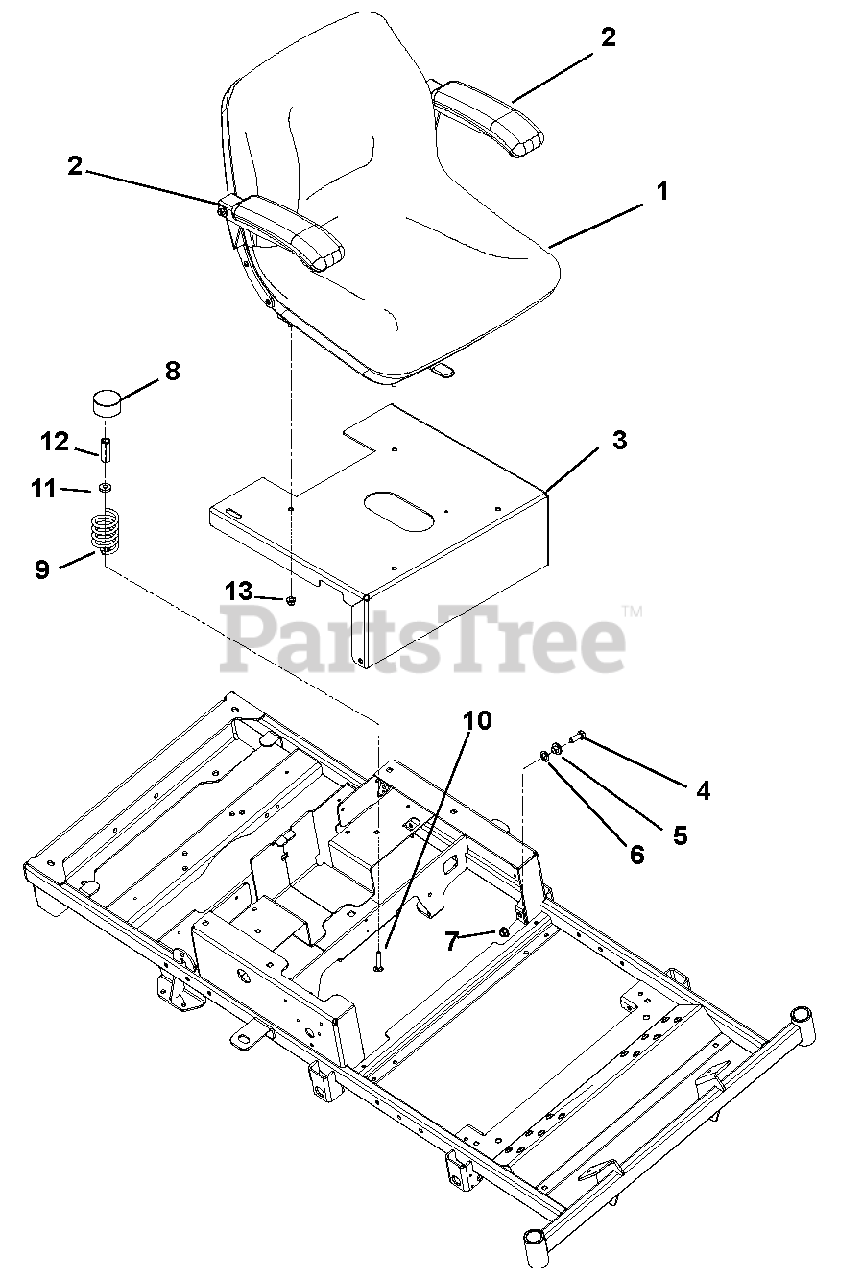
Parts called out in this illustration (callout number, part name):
1	SEAT, MILSCO XB-180
2	KIT, SEAT ARM RESTS
3	SEAT PLATE
4	@BLT-HEX .38-16X1.00 GR5 YWZC
5	BSHG-FLG .385X.500X.875X.406
6	WSHR-FL-STL .52X.827X.062 YWZC
7	@NUT-LK-NYL-FLG .38-16 YWZC
8	HUB CAP
9	SPRING, SEAT
10	@BLT-RDHDSQNK .31-18X1.50 G5YZ
11	WSHR-FL-STL .328X.87X.179 YWZC
12	NUT, COUPLING 5/16-18 X 1 3/4
13	@NUT-LK-NYL-FLG .31-18 YWZC
